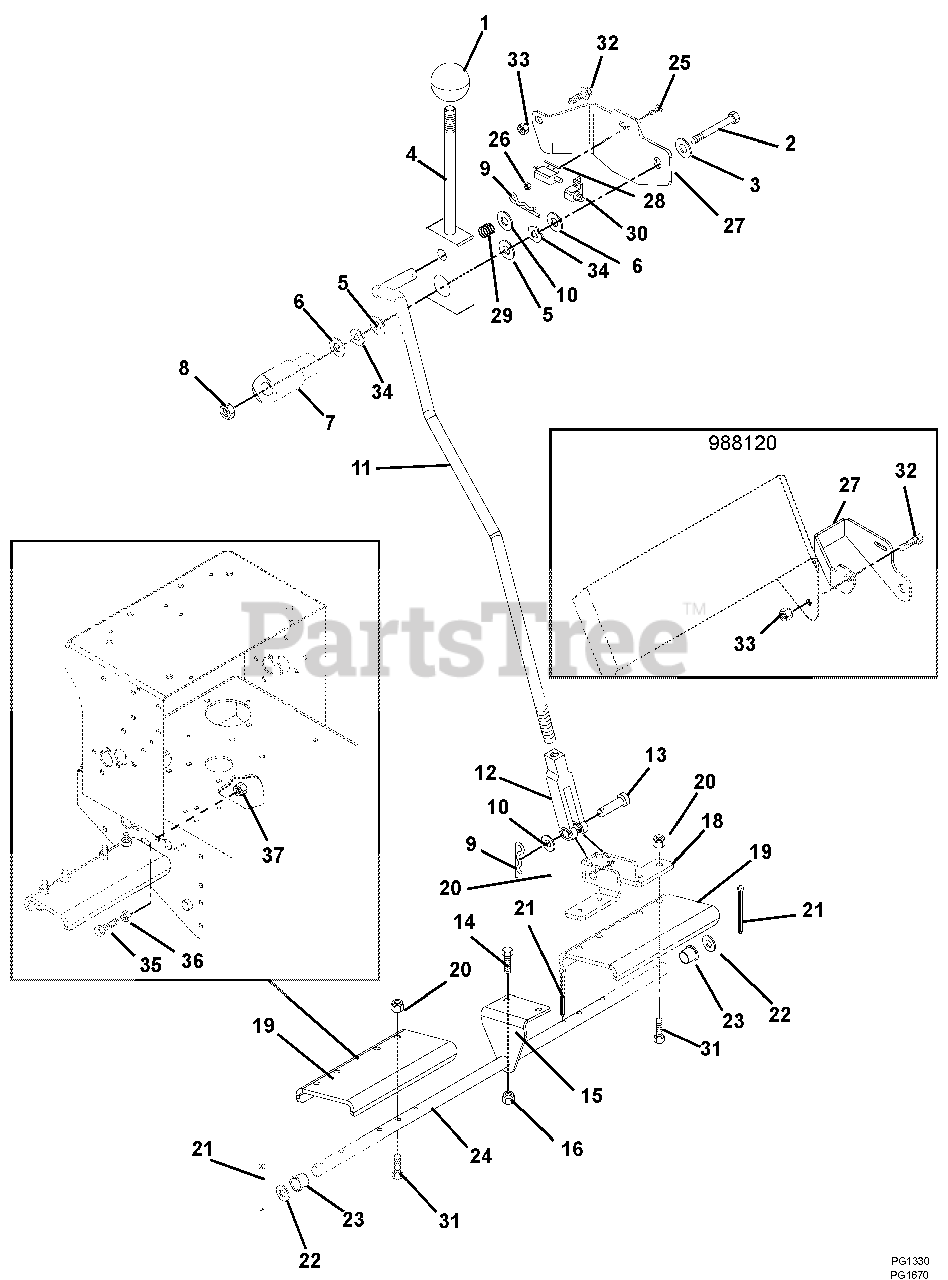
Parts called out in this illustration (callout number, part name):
1	Knob, Ball-Black 1-.41, .375-1
2	Bolt-Hex .44-14 x 4.5 Grade 5
3	Washer-Flat-Steel .50 x 1.25 x .083
4	Weldment- Handle
5	Washer-Flat-Nylon .76 x 1.25 x .030
6	Washer-Flat-Steel .76 x 1.38 x .062
7	Pivot, Brake
8	Nut-Locking-Hex .44-14
9	Pin-Hair Internal .08 x .18 x 1.18
10	Washer-Flat-Steel .406 x .812 x .065
11	Rod, Brake (105, 108, 123, 126)
12	Clevis,.38-24 Adjustable
13	Pin-Clevis .37 x 1.75
14	Bolt-Hex .38-16 x 1.00 Grade 5
15	Bracket, Brake Shaft
16	Nut-Locking-Nylon .38-16
17	Bolt-Hex .25-20 x 1.50 Grade 5
18	Brake, Arm
19	Pad, Brake
20	Nut-Locking-Nylon .25-20
21	Pin-Cotter .12 x 1.00
22	Washer-Flat-Steel .656 x 1.31 x .095
23	Bushing-Flange .63 x 1.00 x .625 Nylon
24	Brake, Shaft
25	Screw-Machine 10-24 x .75 Hex Washer Head
26	Nut-Locking-Nylon 10-24 with Insert
27	Bracket, Parking Brake Switch (105, 108, 123, 126)
28	Switch, Interlock
29	Spring-Compression .045 x .60 x .75
30	Boot, Rubber
31	Bolt-Hex .25-20 x 1.25 Grade 5
32	Bolt-Serrated Hex Flange Washer Head .25-20 x .75 (105, 108, 123, 126)
33	Nut-Locking-Top-Flange .25-20 (105, 108, 123, 126)
34	Washer-Wave .076 x 1.12 x .080
35	Bolt-Hex .38-16 x 1.75 Grade 5
36	Nut-Hex .38-16
37	Nut-Locking-Nylon .38-16
